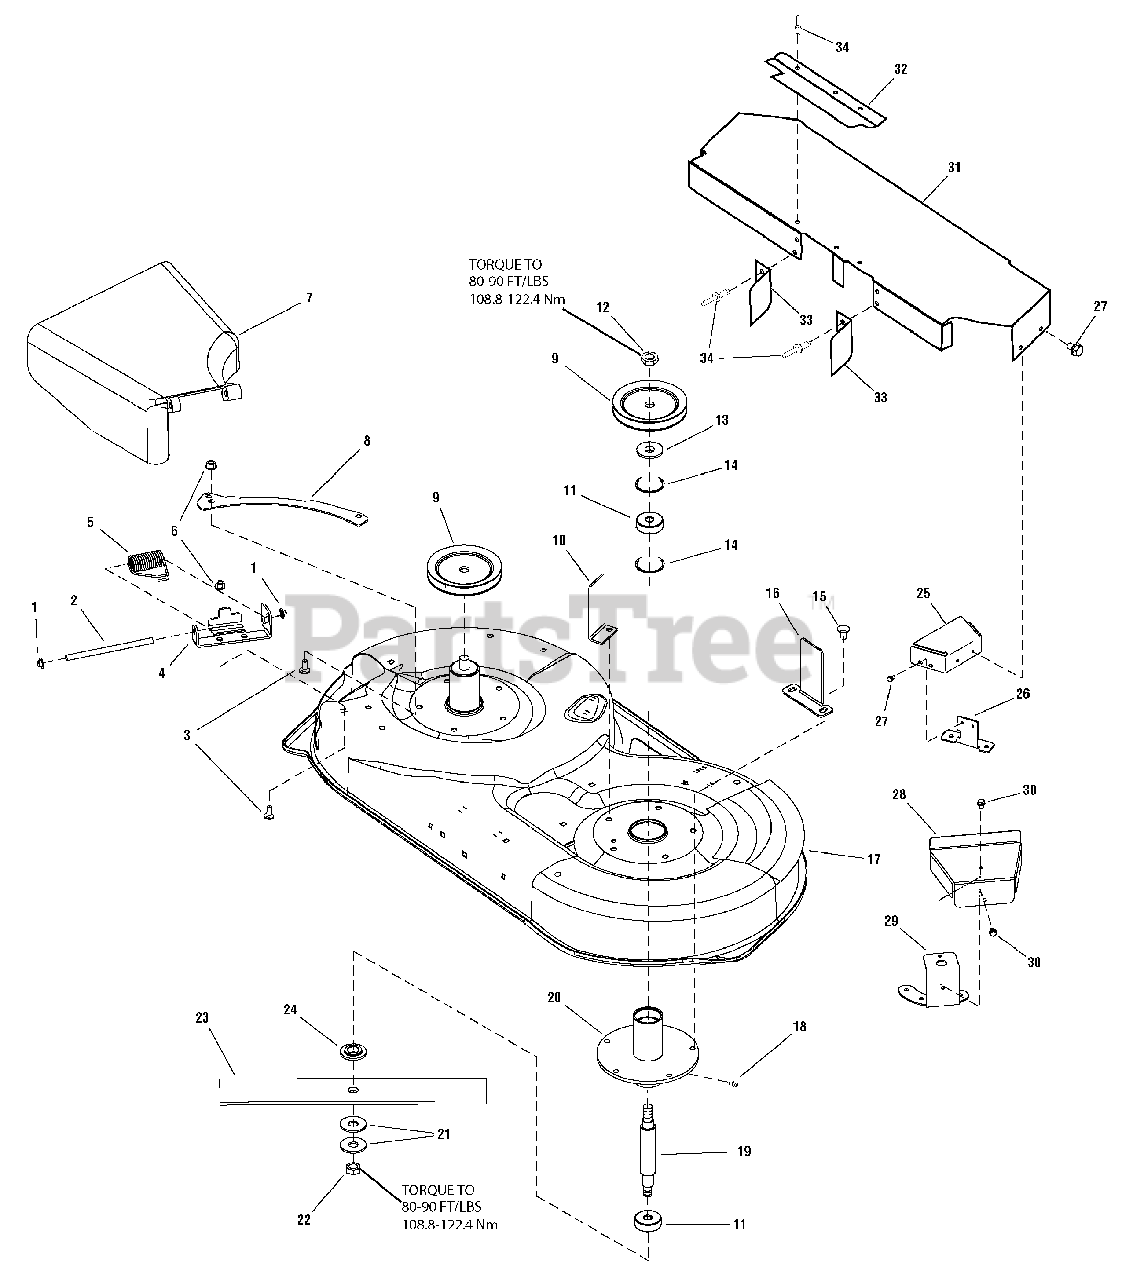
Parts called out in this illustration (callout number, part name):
1	NUT, Push, 3/8
2	ROD, Deflector
3	BOLT, Carriage, 5/16-18 x 3/4
4	BRACKET, Hinge 9GA
5	SPRING, Torsion
6	NUT, Hex, Flange Whizlock, 5/16-18
7	DEFLECTOR & SUPPORT ASSEMBLY, Chute Riveted
8	PLATE, Rear
9	PULLEY, 5.25
9	PULLEY, 5.50
9	PULLEY, 7.00
10	UPSTOP, "L" 10GA
11	BEARING, Upper
12	NUT, Hex Lock, ESNA Light, 5/8-18, Thin
13	SPACER, Pulley, 1.755" OD, .655" ID, .280" Thick
14	RETAINING RING, Extension, 1-3/4
15	SCREW, Hex, Washer Head, Taptite, 3/8-16 x 3/4
16	UPSTOP, "L" 10GA
17	HOUSING, 42"
17	HOUSING, 38"
18	FITTING, Grease
19	SHAFT, Spindle, 7.181" Long
20	TUBE & PLATE ASSEMBLY, Spindle
21	WASHER, Belleville
22	NUT, Hex 9/16-18
23	BLADE, 42" Mower, 21.16" Long
23	BLADE, 38" Mower, 19.49" Long
24	WASHER, Spindle Blade Powdered Metal
25	COVER, Spindle
26	SUPPORT, Spindle Cover
27	SCREW, Tapitite 1/4-20 x 1/2
28	COVER, Pulley
29	SCREW, Taptite 5/16-20 x 1/2
30	LOCKWASHER, Interior Tooth 5/8
31	GUARD, Pulley
32	GUARD, Belt
33	GUARD, Belt
34	RIVET, Pop
